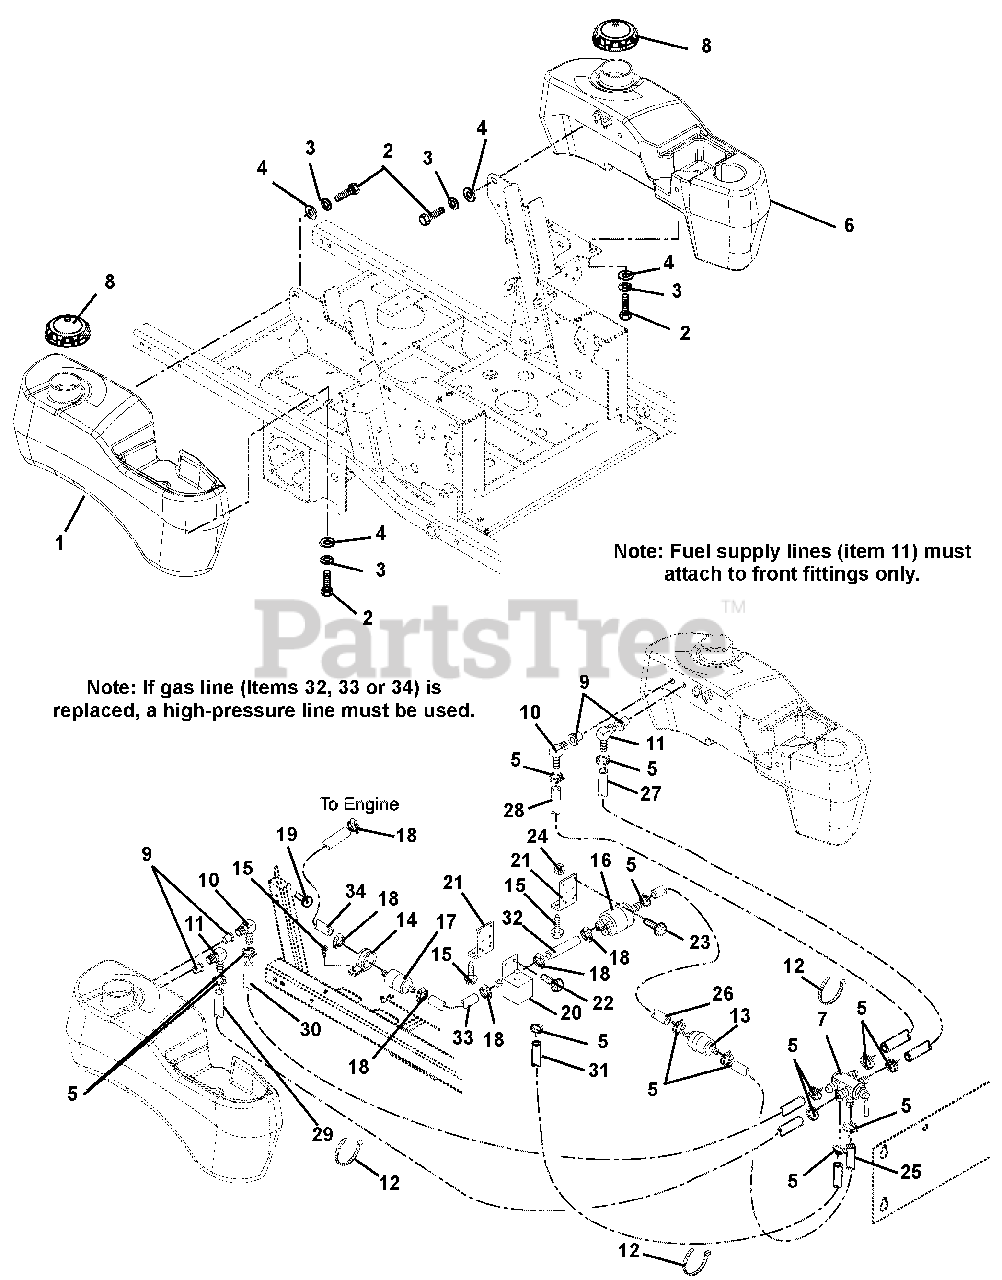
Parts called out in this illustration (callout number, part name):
1	Fuel Tank, Right Hand
2	Bolt, Hex .31-18 x .75 Grade 5
3	Washer, Locking .31 x .078
4	Washer, Flat Steel .38 x .875 x .083
5	Hose, Clamp
6	Tank, Left Hand Fuel (EYE-Q) 200 Series-EFI
7	Valve, Fuel
8	Cap, Gas
9	Bushing (Black in color. Does not replace or interchange with orange colored grommet.)
10	Fitting, Tank Elbow
11	Fitting, Tank Elbow
12	Tie, Cable
13	Filter, Fuel .31
14	Clamp, 2.18
15	Screw, Tapping .38-16 x .50 Hex Washer Head
16	Pump, EFI Fuel
17	Filter, Fuel
18	Hose Clamp
19	Tube Clip .75
20	Regulator, EFI Fuel
21	Bracket, Pump and Regular Mounting
22	Screw, Tapping .25-20 x .37 Hex Washer Head
23	Screw, Machine 10-24 x .50 Hex Washer Head
24	Nut, Locking Top 10-24
25	Hose, .31 I.D. Low Pressure
26	Hose, .31 I.D. Low Pressure
27	Hose, .31 I.D. Low Pressure Left Hand
28	Hose, .31 I.D. Low Pressure Left Hand
29	Hose, .31 I.D. Low Pressure Right Hand
30	Hose, .31 I.D. Low Pressure Right Hand
31	Hose, .31 I.D. Low Pressure
32	Gas Line .31 I.D. High Pressure
33	Gas Line .31 I.D. High Pressure
34	Gas Line .31 I.D. High Pressure
